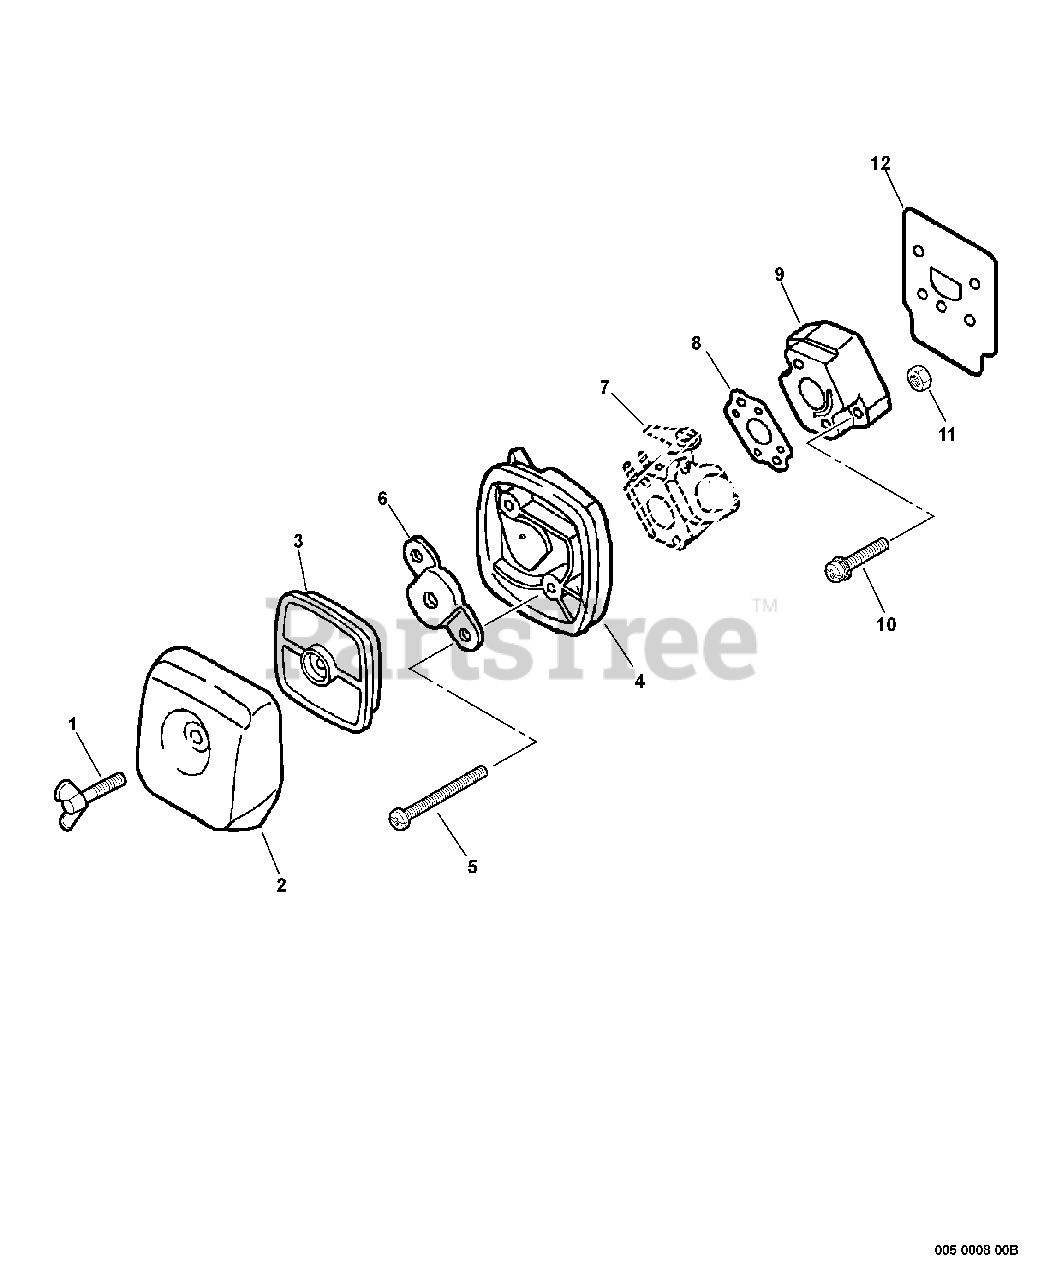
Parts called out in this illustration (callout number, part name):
1	THUMBSCREW
2	COVER, AIR FILTER - GRAY
3	FILTER, AIR - SINGLE LAYER
4	CASE, AIR FILTER - GRAY
5	SCREW - 5X65
6	PLATE, PREVENT
7	CARBURETOR
8	GASKET, INTAKE
9	INSULATOR, INTAKE
10	SCREW - 5X20
12	SHIELD, INTAKE
